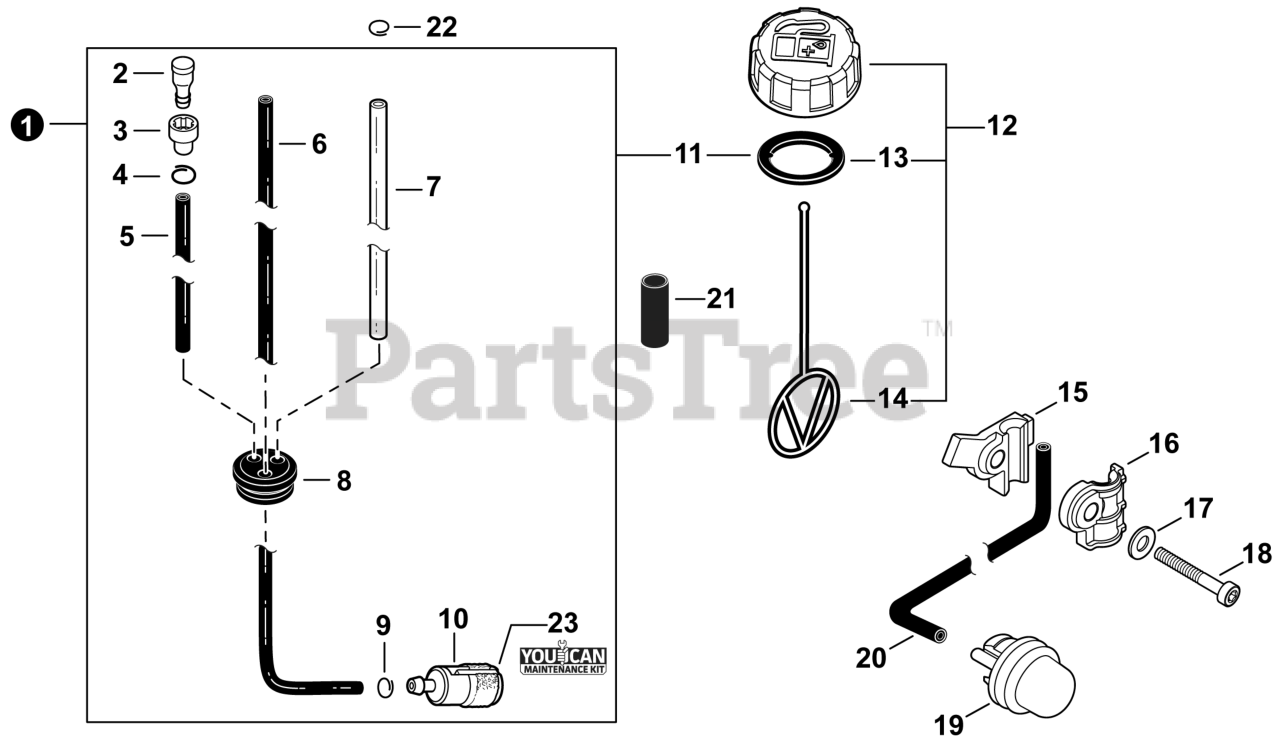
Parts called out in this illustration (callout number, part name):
1	FUEL SYSTEM KIT
2	VENT ASSY
3	HOLDER, VENT
4	CLIP Ø6.5 MM
5	PIPE, FUEL 3×6×130 BLACK
6	PIPE, FUEL 3×5×240 BLACK
7	PIPE, FUEL RETURN 2.4×5×170
8	GROMMET, FUEL
9	CLIP Ø6
10	FILTER, FUEL
11	GASKET, FUEL CAP
12	CAP ASSY, FUEL
13	GASKET, FUEL CAP
14	CONNECTOR, CAP L= 100 MM
15	CLAMP, LOWER
16	CLAMP, UPPER
17	WASHER, FLAT 5.5×10×0.8
18	BOLT, TORX 5×25
19	BULB, PURGE
20	PIPE, PURGE 2.5×5×140
21	TUBE, FUEL LINE 16×18×L40
22	CLIP Ø6
23	TUNE-UP KIT - YOUCANT
